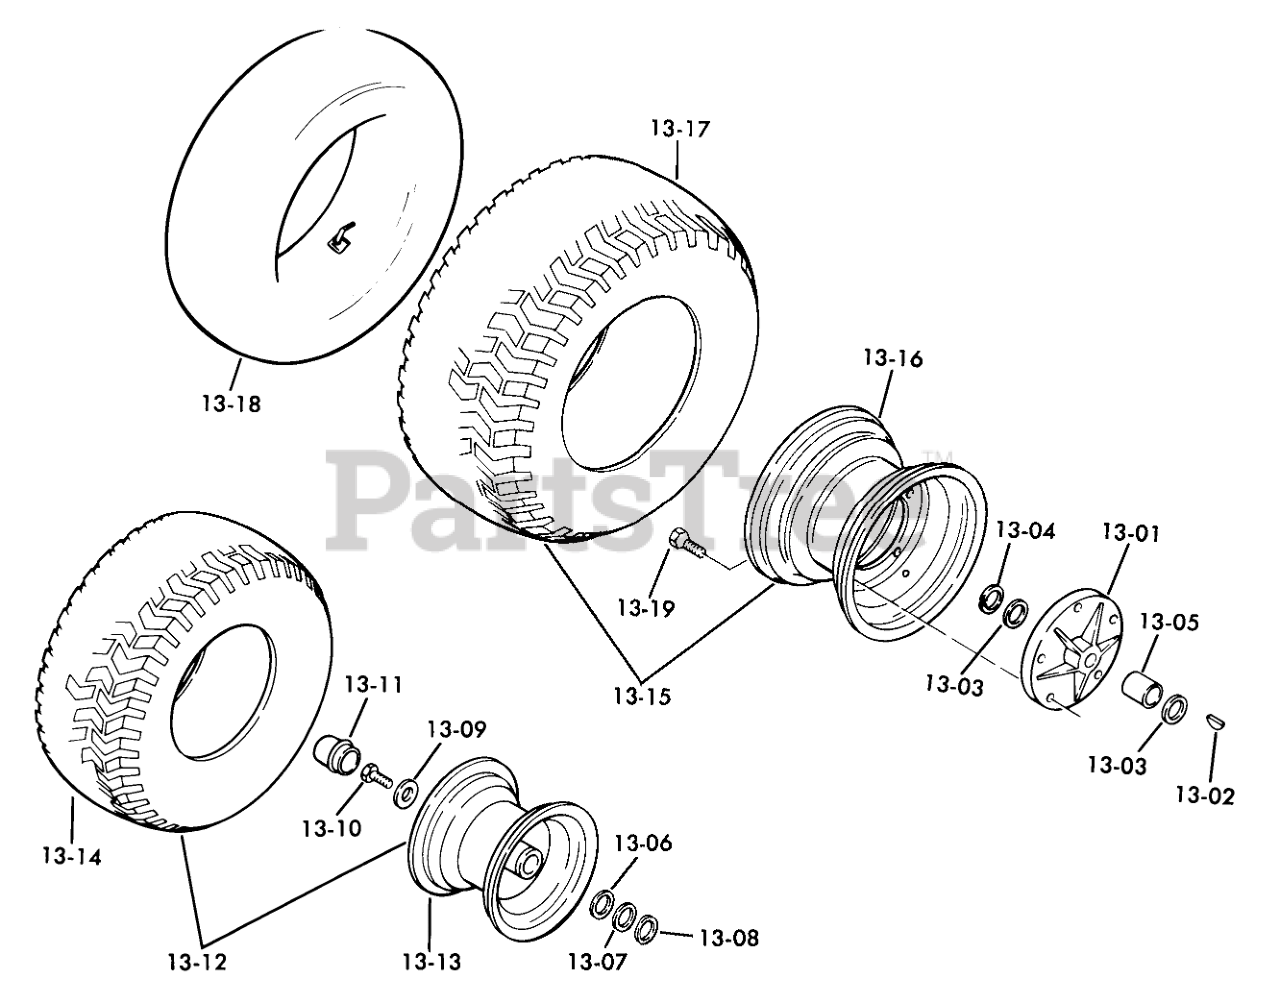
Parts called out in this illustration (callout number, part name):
13-01	Wheel Hub, Rear Axle
13-02	WOODRUFF KEY
13-03	WASHER
13-04	RING-SNAP, EXTERNAL
13-05	Spacer-R.H. Wheel
13-06	Washer
13-07	Pulley-Idler
13-08	WASHER
13-09	WASHER
13-10	Bolt
13-11	HUB CAP
13-12	Assy-Wheel & Tire Front
13-12	Front Wheel
13-13	Front Wheel
13-13	Rim
13-14	TIRE
13-15	Rear Wheel and Tire Assembly (A-100)
13-15	Wheel and Tire
13-16	Wheel
13-17	TIRE 18 X 9.50-8
13-17	TIRE 18 X 8.50 X 8
13-18	Tube-Inner
13-18	Tube-Front Tire
13-19	LUG BOLT
